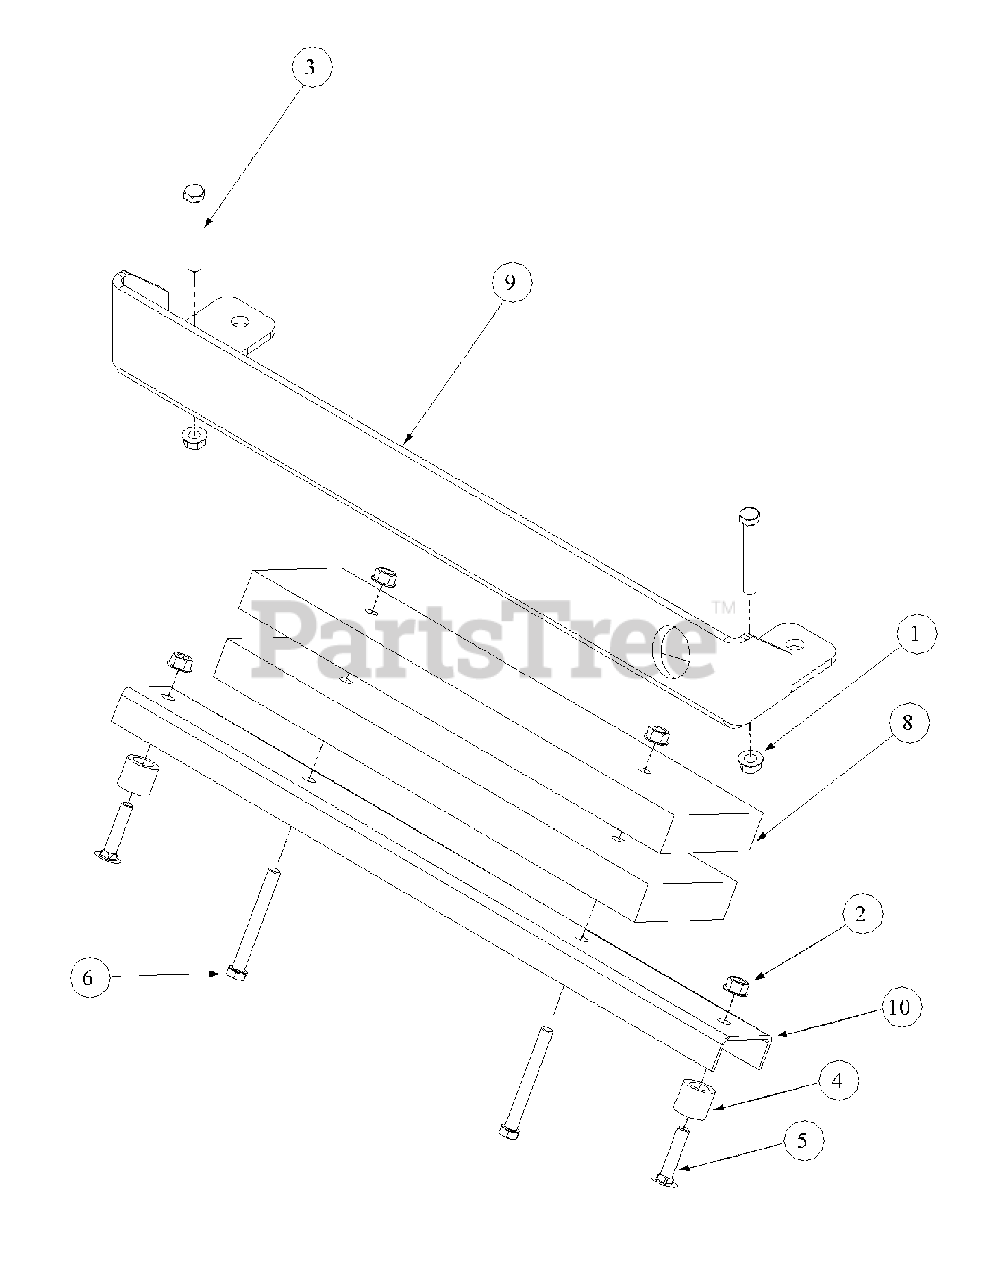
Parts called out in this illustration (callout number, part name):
1	Hex Nut, 1/2-13, Insert Lock
2	Nut, Hex 3/8-16 Flange Lock
3	HHCS, 1/2-13, 3.00
4	Spacer Crossbar
5	Carriage Bolt, 3/8-16, 1.75
6	HHCS, 3/8-16, 3.25
9	Rear Bumper Plate
10	Bumper Cross Bar-Rear
